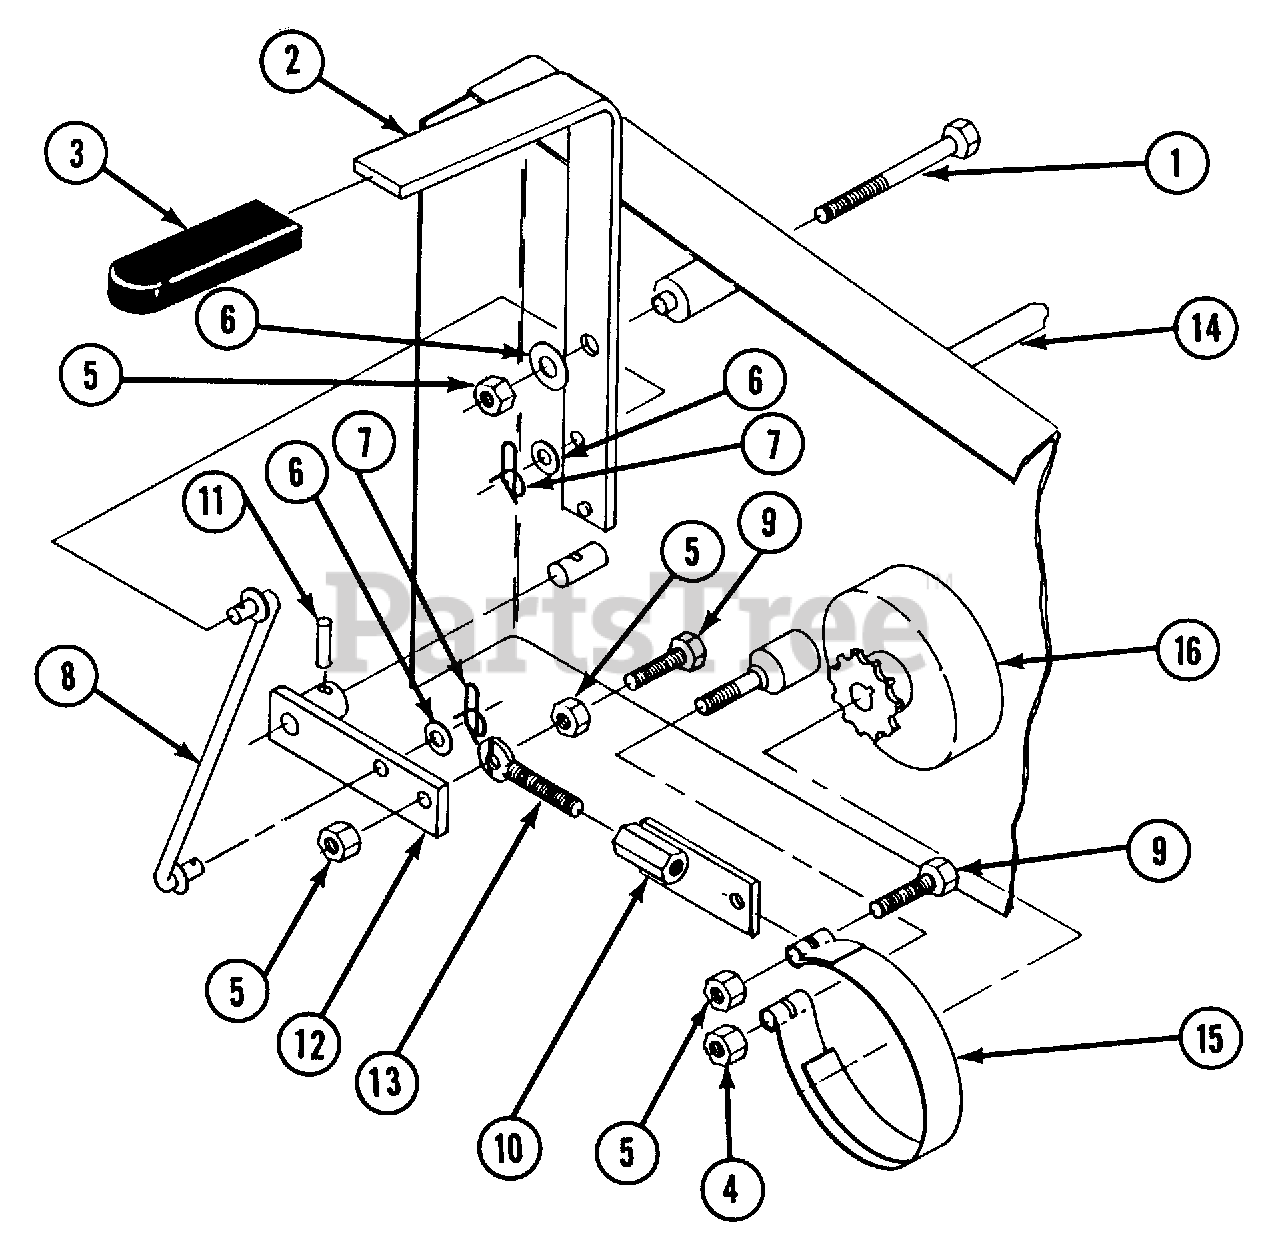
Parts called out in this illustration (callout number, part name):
1	CAPSCREW, HEX. 5/16-18 X 3 GR.5
2	BRAKE HANDLE WLDT.
3	GRIP, DIPPED VINYL, 1/4 X 1
4	LOCKNUT, HEX, 3/8-16 W/NYLOC
5	LOCKNUT, HEX, 5/16-18 W/NYLOC
6	WASHER, 5/16 STD. FLAT
7	COTTER, RUE RING, 5/16-3/8 PIN
8	BRAKE-ROD LINK WLDT,
9	CAPSCREW, HEX, 5/16-18 X 1-1/4 GR. 5
10	BRAKE LINK WLDT.
11	PIN, SPIROL, 3/16 X 1, LIGHT DUTY
12	BRAKE ARM WLDT
13	THUMB SWIVEL
14	BRAKE CROSS SHAFT
15	BRAKE BAND, 4-3/16 DIA 3/4 WIDE
16	SPROCKET/BRAKE DRUM WLDT
